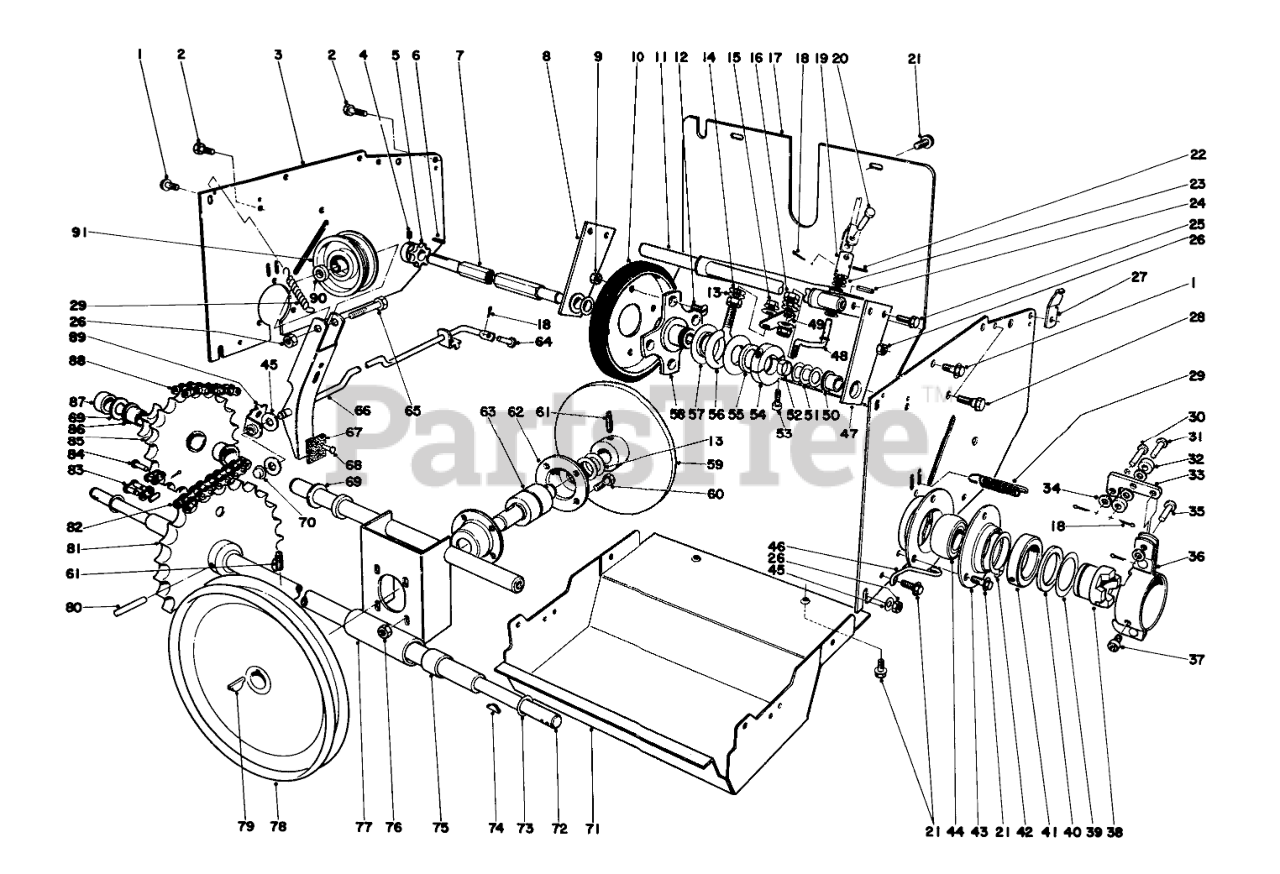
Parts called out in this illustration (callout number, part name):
1	SCREW-HHF
2	SCREW-HHFTF
3	Side Plate Drive
4	SCREW-HSH
5	SPROCKET
7	FRICTION WHEEL SHAFT
8	Hex Shaft Mount (Incl. Ref. #50)
9	Nut
10	Disc
11	Bracket Dead Shaft
12	5/16-18X5/8 FLT HD MS
13	Washer
14	WASHER-SPRING
15	NUT-LOCK, FLANGE
16	Nut
17	REAR COVER R
18	PIN-COTTER
19	U JOINT TUBE
20	CLEVIS PIN
21	SCREW-HWH
22	PIN-SPRING
23	Spacer
24	PIN-ROLL
25	SCREW-HWHTF
26	NUT-HEX
27	HANDLE MTG BRKT
28	SHOULDER SCREW
29	EXTENSION SPRING
30	PIN-CLEVIS
31	PIN-CLEVIS
32	CLUTCH ROLLER
33	CLUTCH CAM ARM
34	WASHER-FLAT
35	PIN-CLEVIS
36	CLUTCH MT BRKT ASM
37	Hex Socket Capscrew
38	Clutch Wheel
39	THRUST WASHER
40	THRUST BEARING
41	CLUTCH MOUNT COLLAR
42	RING-RETAINING, EXTERNAL
43	BEARING FLANGE
44	BEARING
45	WASHER-FLAT
46	Clutch Retainer
47	Hex Shaft Mount(Incl. Ref. #50)
48	CONNECTION ROD
49	SHIFT ROD PIVOT
50	BUSHING
51	WASHER-FLAT
52	SPLIT SPACER
53	SCREW-HSH
54	Collar
55	WASHER-THRUST
56	SLIDER RING COLLAR
57	SLIDER RING
58	TRACTION DISC HUB
59	Friction Plate
60	SCREW-HH
61	Set Screw
62	HOUSING BEARING
63	Friction Plate Shaft
64	PIN-CLEVIS
65	SCREW-HH
66	Idler (Incl. Ref. #67-68)
67	BRAKE PAD
68	.185 DIA X .375 RT +
69	WASHER-THRUST
70	PUSH NUT
71	LOWER SHIELD R
72	Axle Shaft
73	WASHER
74	1/4X1-1/16 HI-PRO KEY
75	BUSHING
76	NUT-KEPS
77	Bulkhead (Incl. Ref. #75)
78	Pulley
79	KEY-WOODRUFF
80	PIN-GROOVED
81	Sprocket
82	Chain Lower
83	Connecting Link
84	1/4 OFFSET LINK
85	Sprocket (Incl. Ref. #86)
86	3/4ID X 3/4LG BSHG
87	SPACER-IDLER
88	1/4 X 42 CHAIN W/LINK
89	Bracket-Clutch
90	Spacer
91	Idler Pulley
